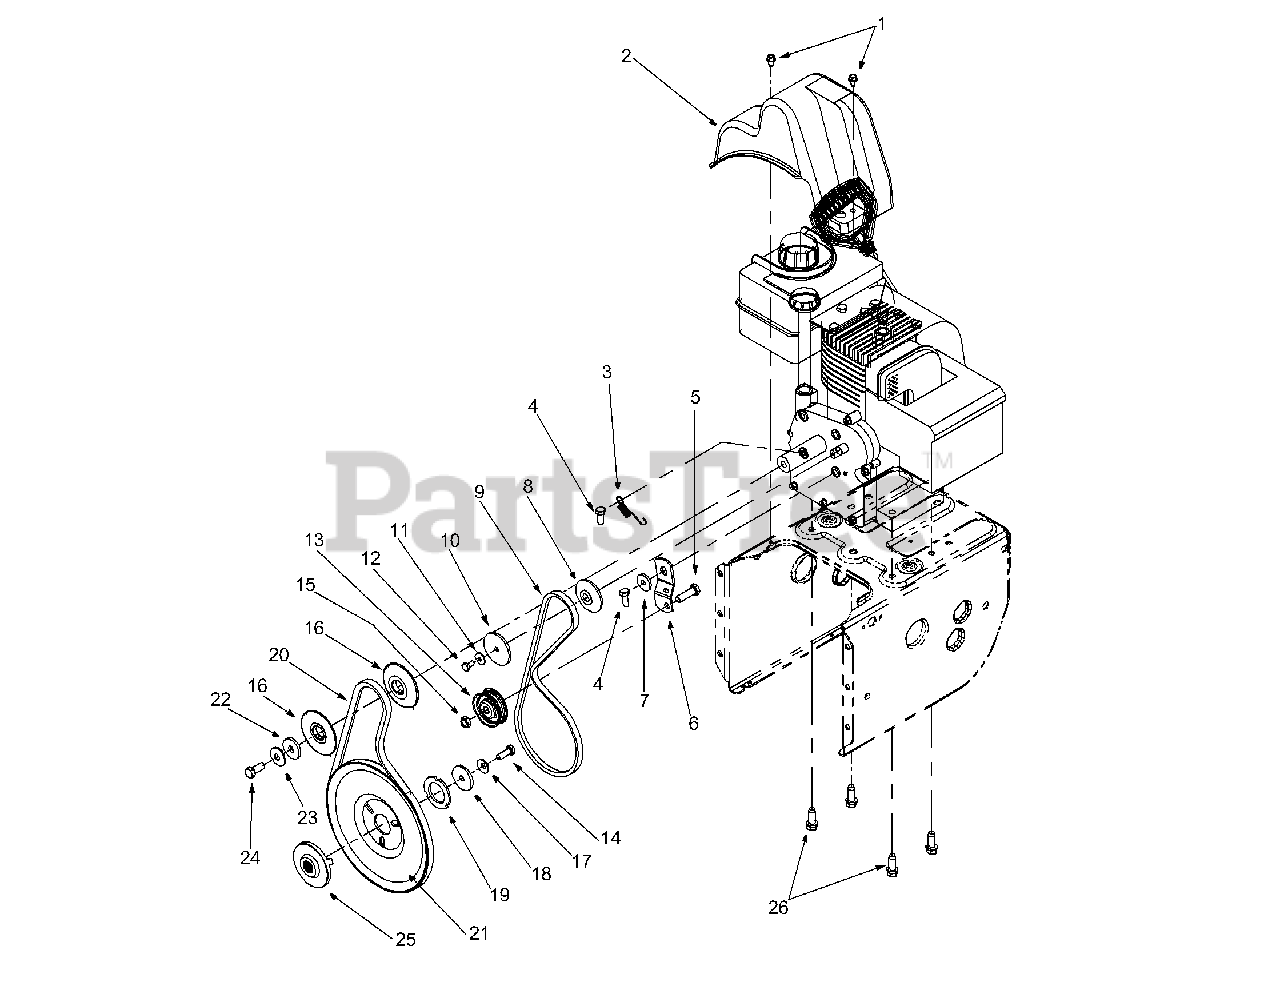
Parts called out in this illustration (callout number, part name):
1	Hex Washer Screw 1/4-20 x.5
2	Belt Cover
3	Extension Spring
4	Hex Screw 5/16-24 x .75
5	Hex Cap Screw 3/8-16 x 1.25
8	Pulley Half
9	V-Belt
10	Pulley Half
11	Bell Washer
12	Hex Cap Screw 1/4-28 x .50
13	Flat Idler
14	Lock Cap Screw 5/16-24
15	Lock Jam Nut 3/8-16
16	Pulley Half
17	Bell Washer
18	Flat Washer
19	Washer
20	Belt
21	Auger Pulley
22	Flat Washer
23	Bell Washer
24	Hex Cap Screw 3/8-24
25	Pulley
26	Hex Washer Screw 3/8-16 x 1.0
